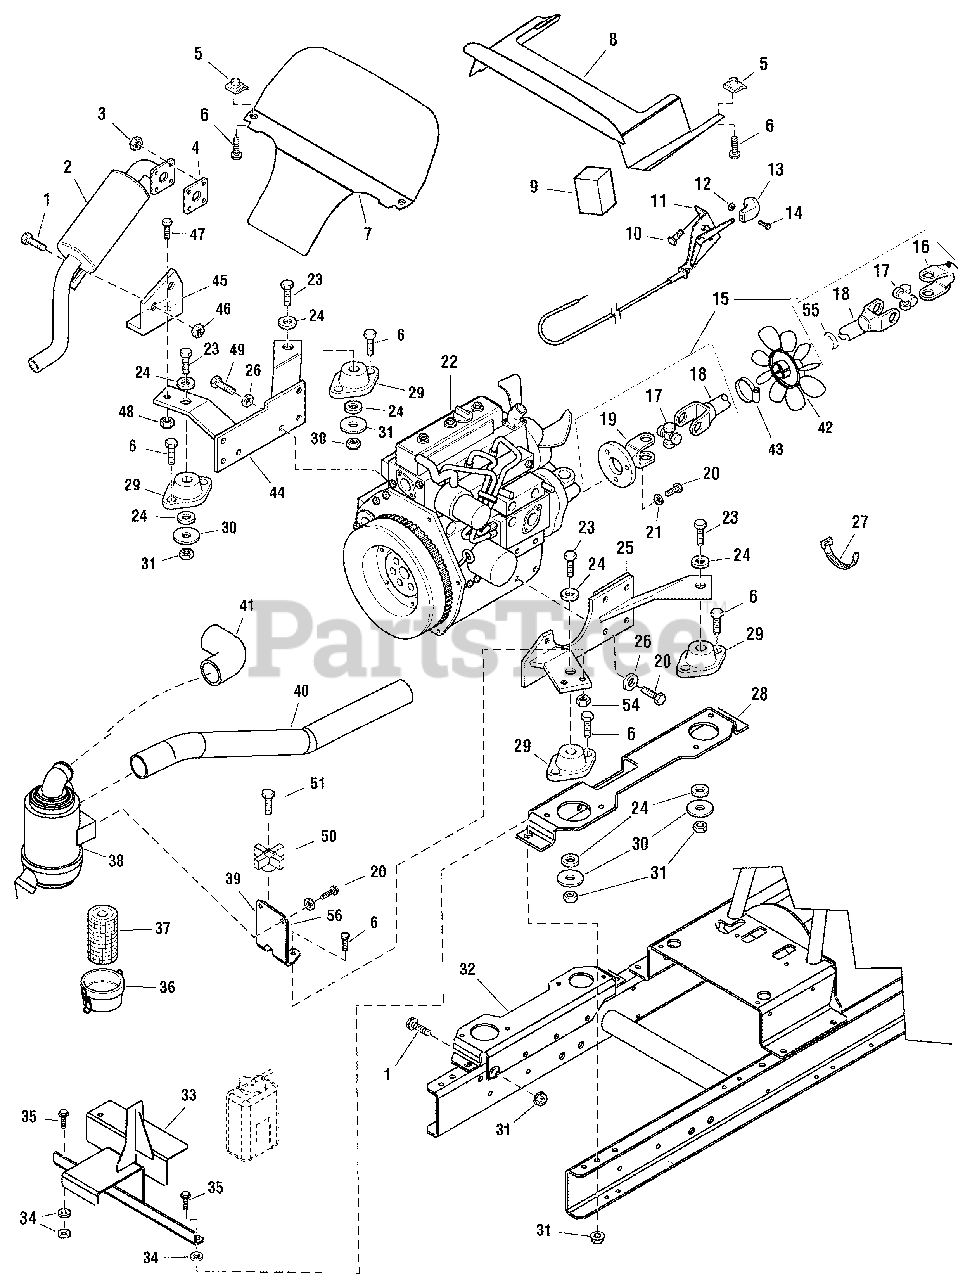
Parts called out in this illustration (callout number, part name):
1	SCREW, Hex Whiz Lock Flange, 3/8-16 x 1
3	NUT
4	BRACKET
5	NUT, Speed, 1/4-20, U Type
6	SCREW, Hex, Washer, Head, Taptite, 5/16-18 x 3/4
7	SHIELD, Hood 18GA
8	BAFFLE, Hood 18GA
9	SEAL, Foam 1-1/2 x 1-1/2, 2.8LG
10	SCREW, Hex, Washer Head, Taptite, 12-24 x 5/8
11	CONTROL, Throttle
12	NUT, Hex Lock, 10-24
14	SCREW, Pan Head, PHILLIPS, 10-24 x 1
15	SHAFT ASSEMBLY, Drive (Includes Ref. Nos. 16, 17, 18 & 19)
16	YOKE, Drive Shaft
17	CROSS & BEARING KIT, Includes Grease Fitting
18	YOKE & TUBE ASSEMBLY
19	YOKE & FLANGE, Drive Shaft
20	CAPSCREW, Hex Head,
21	LOCKWASHER, Spring, 5/16
23	CAPSCREW, Hex Head, 3/8-16 x 2-1/2, G5
24	WASHER, 3/8
25	MOUNT ASSEMBLY, Engine, L.H.
26	LOCKWASHER, Spring, 5/16
27	TIE, Self Locking, 7.31LG
28	MOUNT, Engine, L.H.
29	MOUNT, Engine, Rear
30	WASHER, 1/2
31	NUT, Hex KEPS, 3/8-16 Conical Washer
32	MOUNT, Engine, R.H.
33	HOLD DOWN ASSEMBLY, Battery
34	WASHER, 3/8
35	SCREW, Hex, Whiz Lock, Flange, 3/8-16 x 1-1/4
36	CAP, Air Cleaner
37	FILTER, Air Cleaner
38	AIR CLEANER ASSEMBLY
39	BRACKET, Air Cleaner
40	HOSE, Air Inlet, 28LG
41	HOSE, Inlet
43	CLAMP, Hose, Worm
44	MOUNT ASSEMBLY, Engine R.H.
45	BRACKET, Muffler
46	NUT, Hex, Flange, 3/8-16, ESNA
47	SCREW, Hex, Whiz Lock, Flange 5/16-18 x 1-1/4
48	NUT, Hex, Flange, 5-16-18, ESNA
49	CAPSCREW, Hex Head
51	CAPSCREW, Hex Head 5/16-18 x 1.500
52	WASHER, 11/32 x 3/4 x 1/16
54	NUT, Hex, 5/16-18
55	TAPE, Double Sided Foam .88 x 4.71
56	DECAL, Air Cleaner
